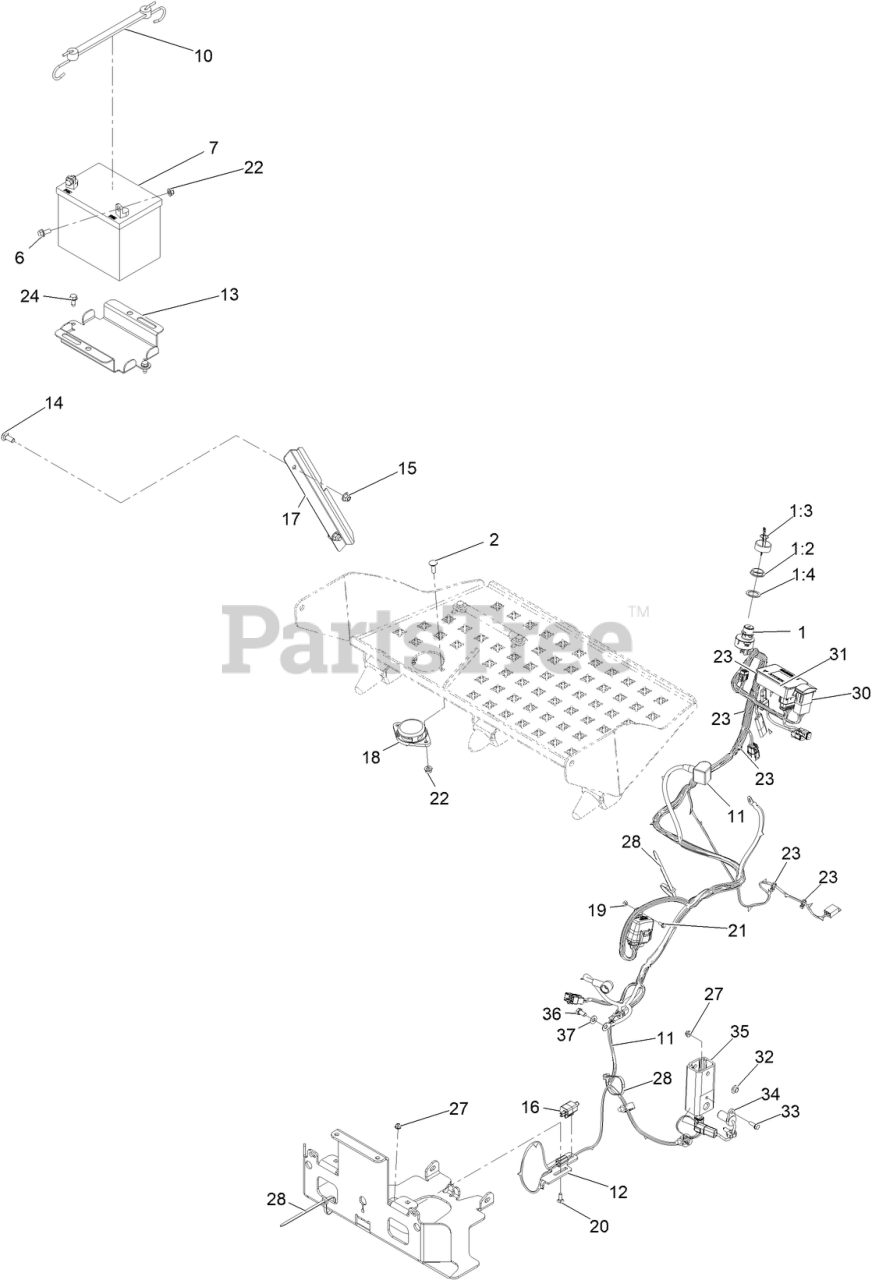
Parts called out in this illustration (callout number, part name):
1	IGNITION SWITCH ASM
1:2	NUT-MOUNTING
1:3	IGNITION KEY SET
1:4	WASHER-BACKUP
2	BOLT-CARR
6	SCREW-HHF
10	HOLDDOWN-BATTERY
11	HARNESS-WIRE
12	MOUNT-SWITCH
13	BRACKET-BATTERY
14	BOLT-CARR
15	NUT-HF, NI
16	SWITCH
17	GUARD-HARNESS
18	SWITCH-SEAT
19	NUT-LOCK, NI
20	BOLT-CARR
21	SCREW-HWH
22	NUT-HF, NI
23	TIE-CABLE
24	SCREW-HWHTF
27	NUT-HF
28	TIE-CABLE
30	SWITCH
31	HOUR METER ASM
32	NUT-PUSH
33	SCREW-HWH
34	SENSOR, QUADRATURE
35	HOUSING-DEPTH CONTROL 30
36	SCREW-HH
37	WASHER-PLAIN
